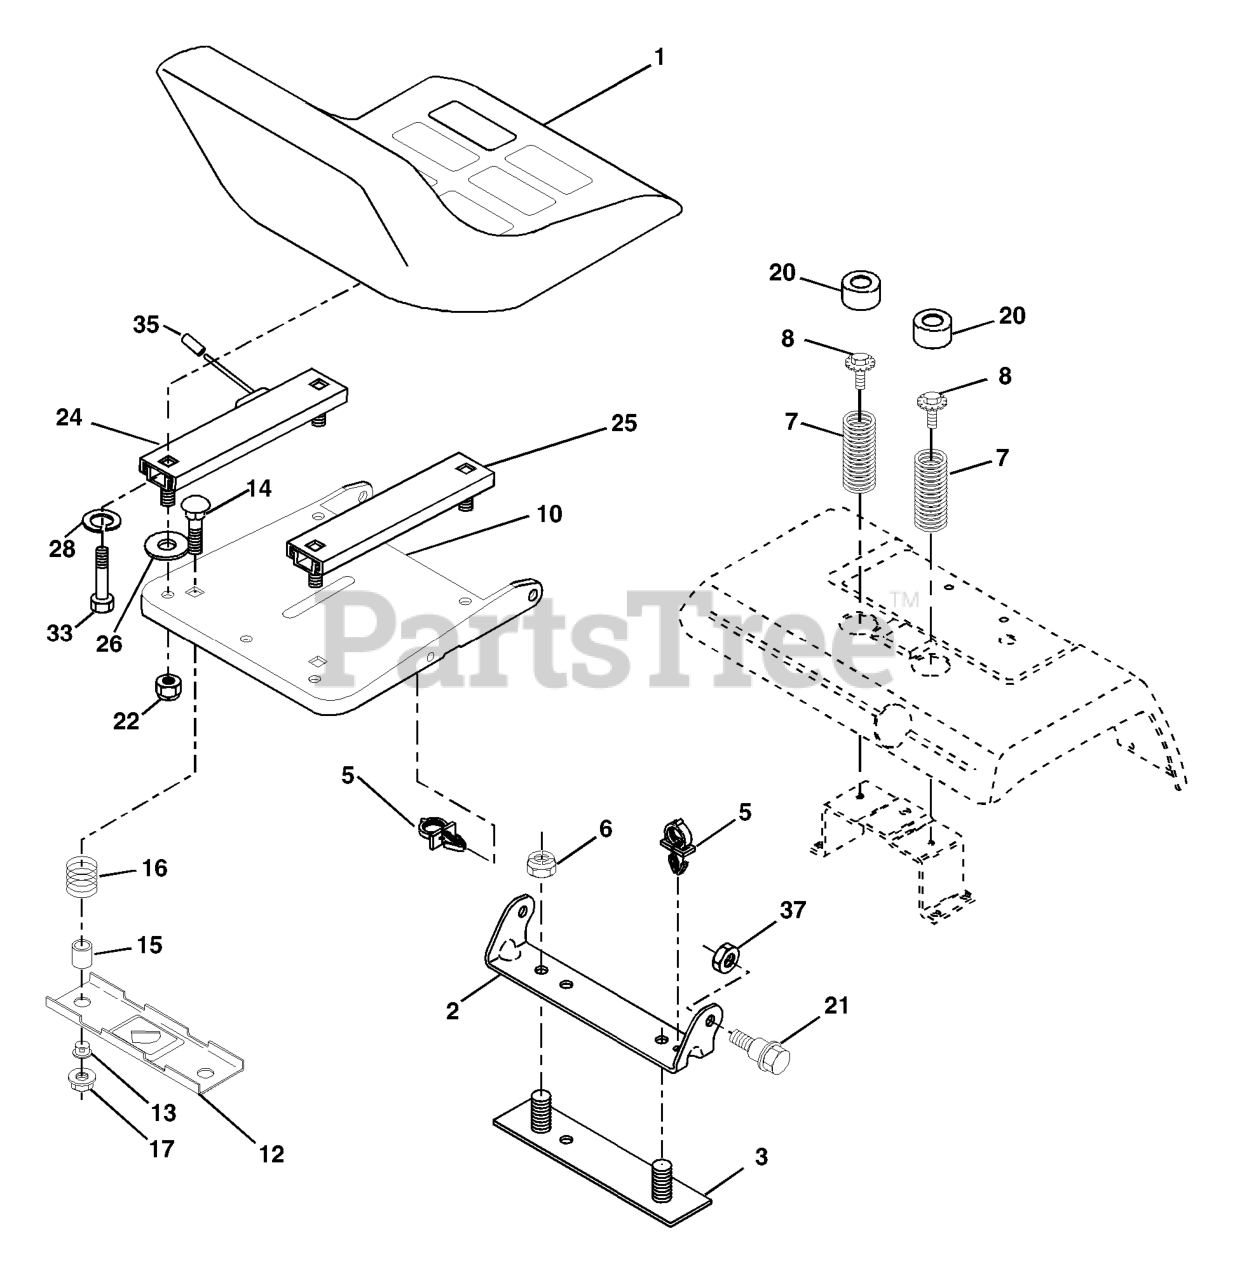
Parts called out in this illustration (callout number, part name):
1	SEAT.XH150.GRY
2	SEAT PIVOT BRKT
3	STRAP
6	NUT
7	SPRING COMPRESSION
8	BOLT.5/16-18UNCX3/4 W/SEMS.BLK
10	PAN SEAT
12	BRKT SWITCH
14	BOLT.ROUND.HEAD.SQUARE.NECK
15	SPACER SPLIT
16	SPRING COMPRESSED
17	NUT T
20	CAP SPRING
21	BOLT.SHOULDER.5/16-18
22	LOCKNUT
24	TRACK SLIDE, SEAT(L)
25	TRACK SLIDE, SEAT(R)
26	WASHER T
33	BOLT.FIN.HEX.5/16-18X3/4
35	CAP
37	NUT.71038.31-18.HEX.NYLOCK
